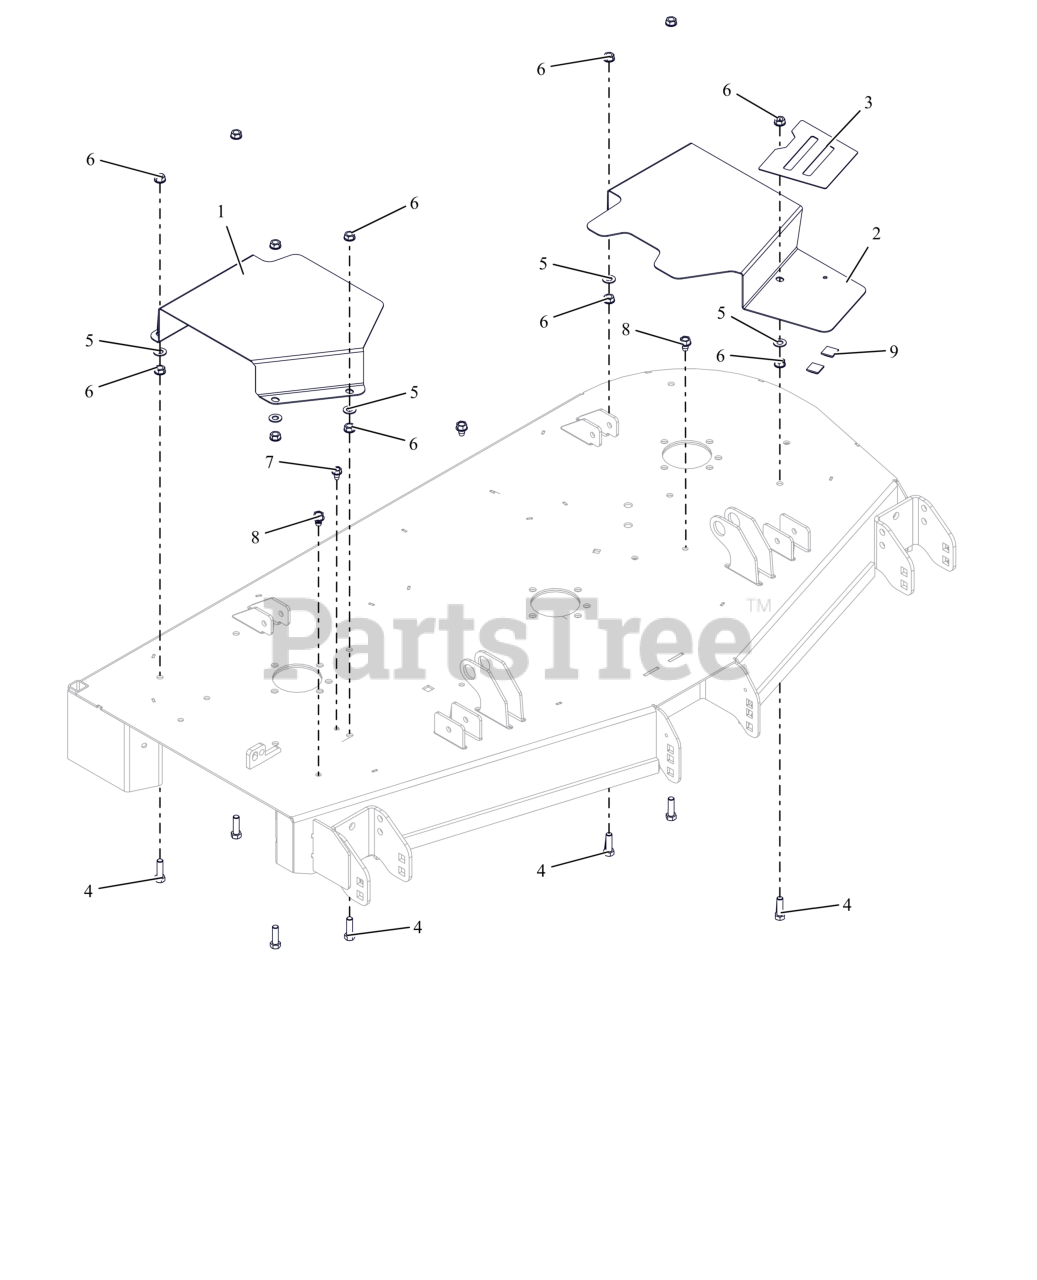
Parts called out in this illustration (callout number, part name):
1	COVER, BELT 52" & 60" RIGHT
2	COVER, BELT 52" LEFT
3	GRIP TAPE 52-60 BELT COVER
4	BLT, HEX .38-16X1.25 G5 ZCC
5	WSHR,FLT .406X.812X.065 ZCC
6	NUT, SPNLK-FLG .38-16 G5 ZCC
7	SCR,TAP .312-18X.50 HWH TR ZCC
8	SCR,TAP .375-16X.50 HWH TR ZCC
